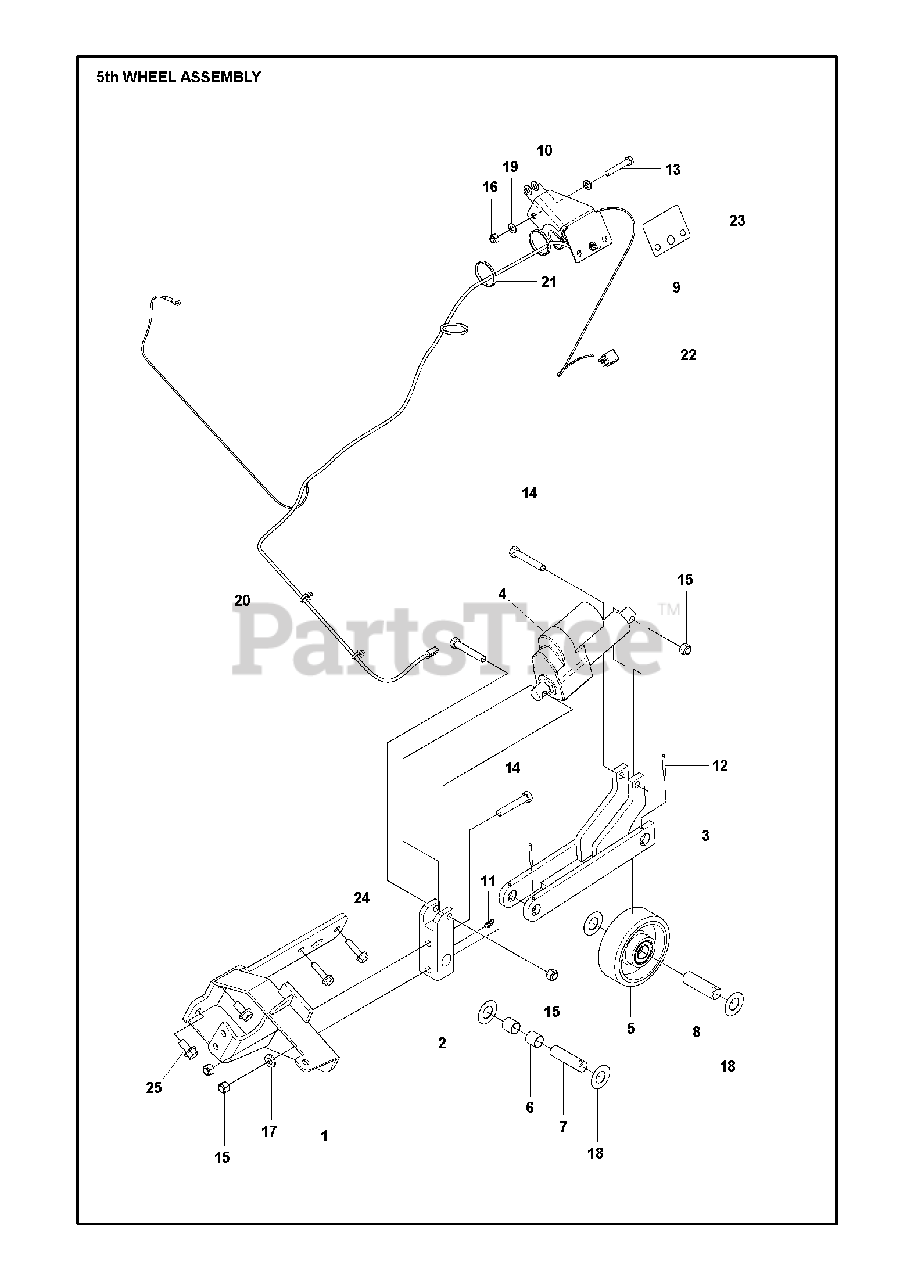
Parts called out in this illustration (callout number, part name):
15	NUT
16	HEXAGON LOCKING NUT
19	WASHER
